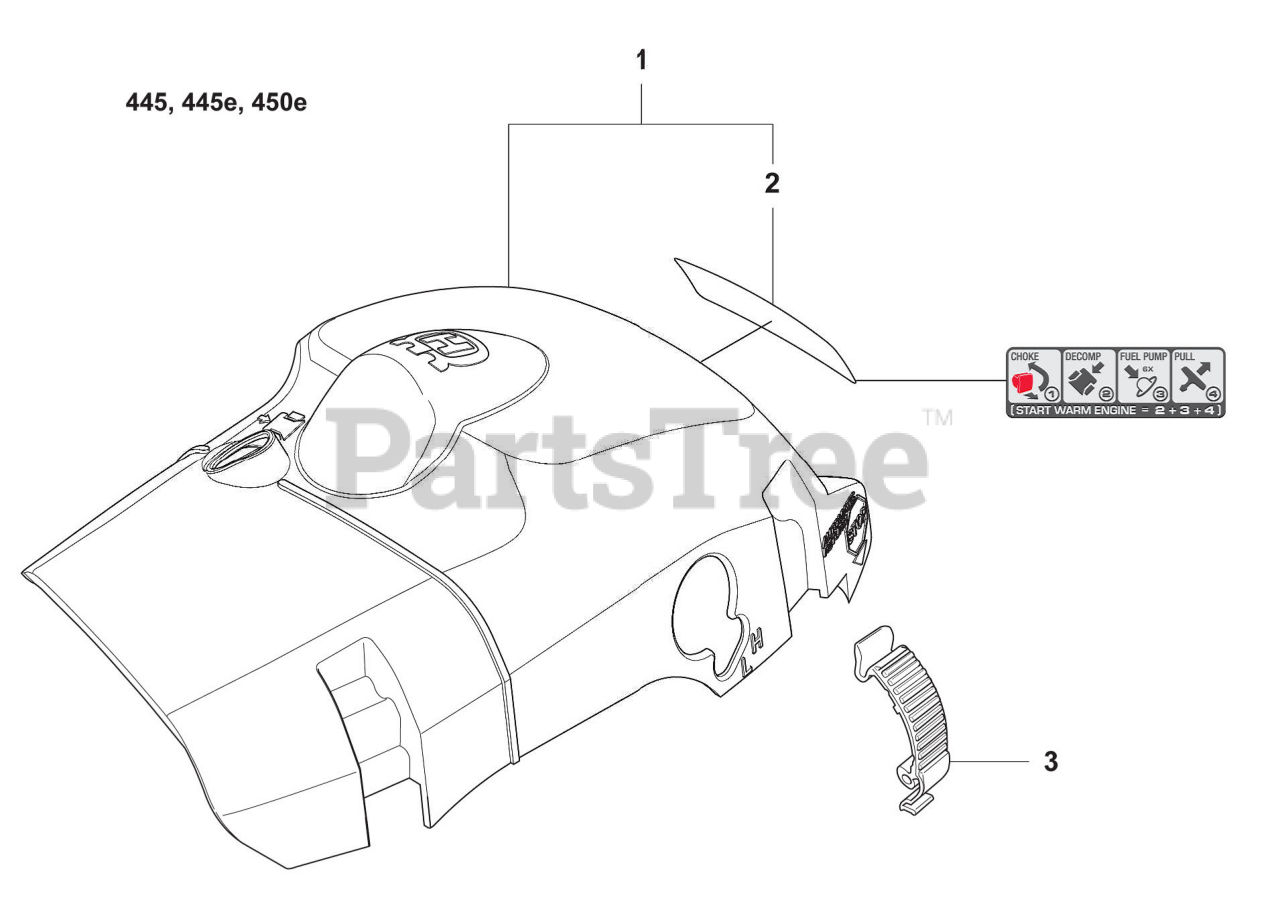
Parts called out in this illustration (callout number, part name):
1	Cylinder Cover Assembly
2	RP LABEL
3	Top Cover Buckle Clip, Orange
